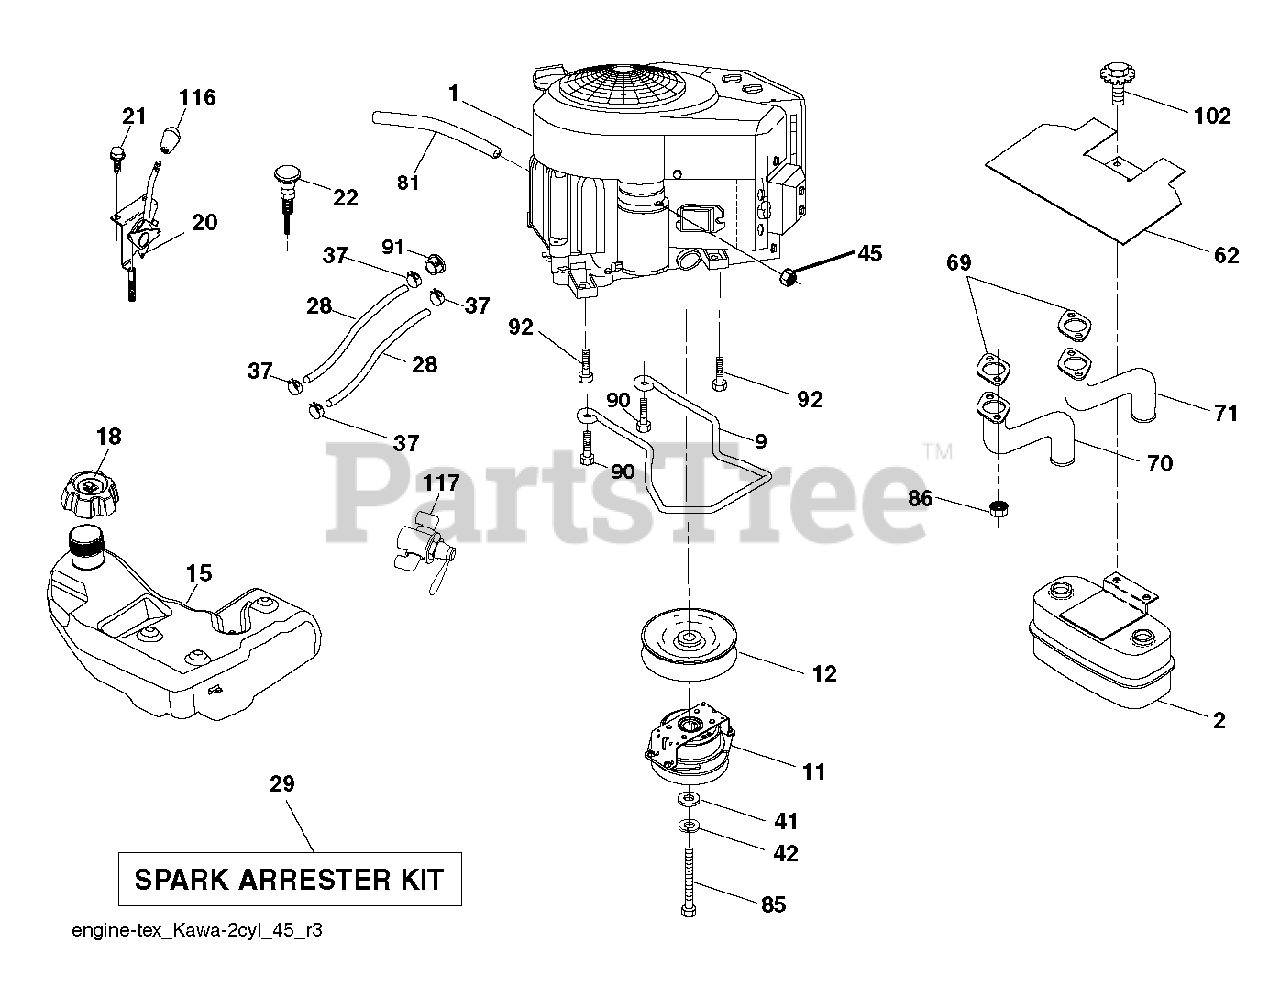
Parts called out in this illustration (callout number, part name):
2	MUFFLER.ASM.TWN.EXTNDED.DFLCTR
9	KEEPER.BELT.ENG.4.25"2.BLT.431
11	CLUTCH. 5.0 PD. 2.5 OFFSET
12	PULLEY.EXTENDED.SHAFT.GROUND
18	CAP.ASSY.FUEL.3".N-EPA.GRY.498
20	CONTROL.THROTTLE.PRO.
21	SCREW.#10 X 0.750.BOS
22	CONTROL, CHOKE
28	REPL BY 532 00 85-43
29	KIT.SPARK ARRESTOR 794945 B&S
37	HOSE CLAMP
42	LOCKWASHER
45	NUT
62	SHIELD.HEAT.MUFFLER
70	TUBE.EXHAUST.LH.FR961/FR730
71	TUBE.EXHAUST.RH.FR961/FR730
81	TUBE, DRAIN OIL ASM.
85	BOLT.HEX.7/16-20X5.GR5.GREEN
86	NUT.HEX.FLANGE.TOPLOCK
90	SCREW 3/8-16X1
91	BUSHING.1.375OD
92	SCREW 3/8-16X1
102	SCREW
116	KNOB - SHIFT
117	VALVE FUEL RESERVE
